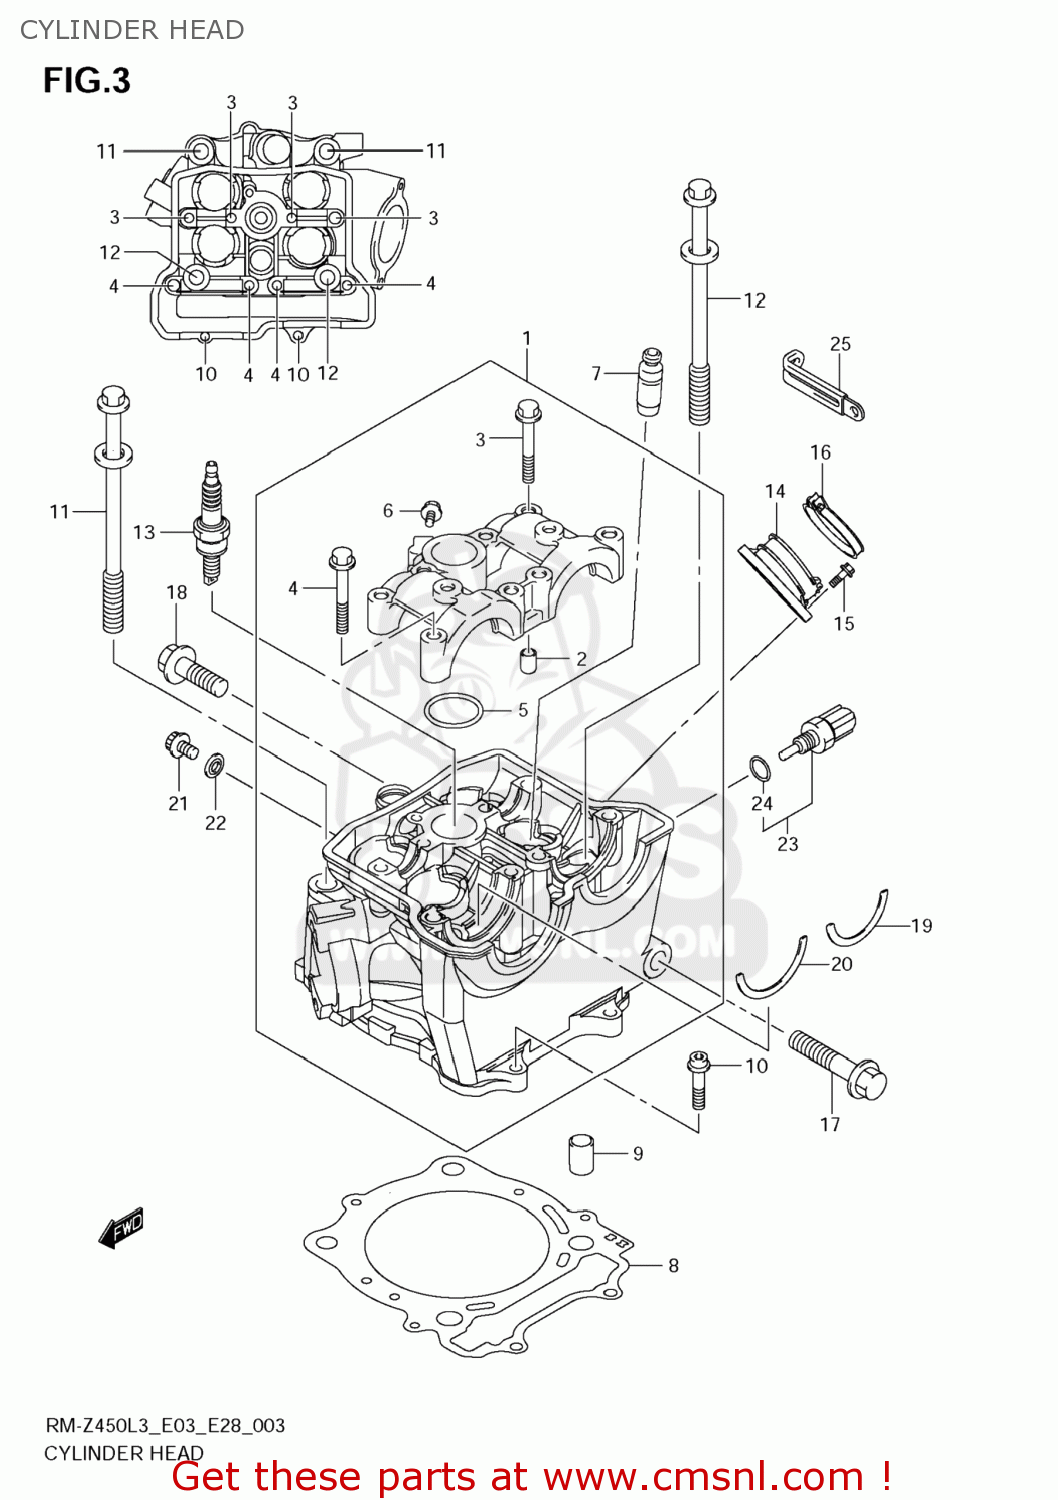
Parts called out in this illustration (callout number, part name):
1	HEAD ASSY,CYLINDER
2	PIN(6.2X8X11)
3	BOLT(6X40)
4	BOLT(6X45)
5	O RING(D:2.4,ID:25.7)
6	BOLT(6X10)
7	GUIDE,VALVE(OS:0.3)
8	GASKET,CYLINDER HEAD (NAS)
9	PIN
10	BOLT
11	BOLT,CYLINDER HEAD(L:140)
12	BOLT,CYLINDER HEAD(L:120)
13	PLUG,SPARK(DIMR8A10)
14	PIPE ASSY,INTAKE
15	BOLT
16	CLAMP,INTAKE PIPE
17	BOLT(10X43)
18	BOLT(10X32)
19	C RING,CAMSHAFT
20	C RING,CAMSHAFT
21	BOLT
22	GASKET(5.8X13X1.2) (NAS)
23	SENSOR,WATER TEMP
24	O RING
25	CLAMP(L:45)
